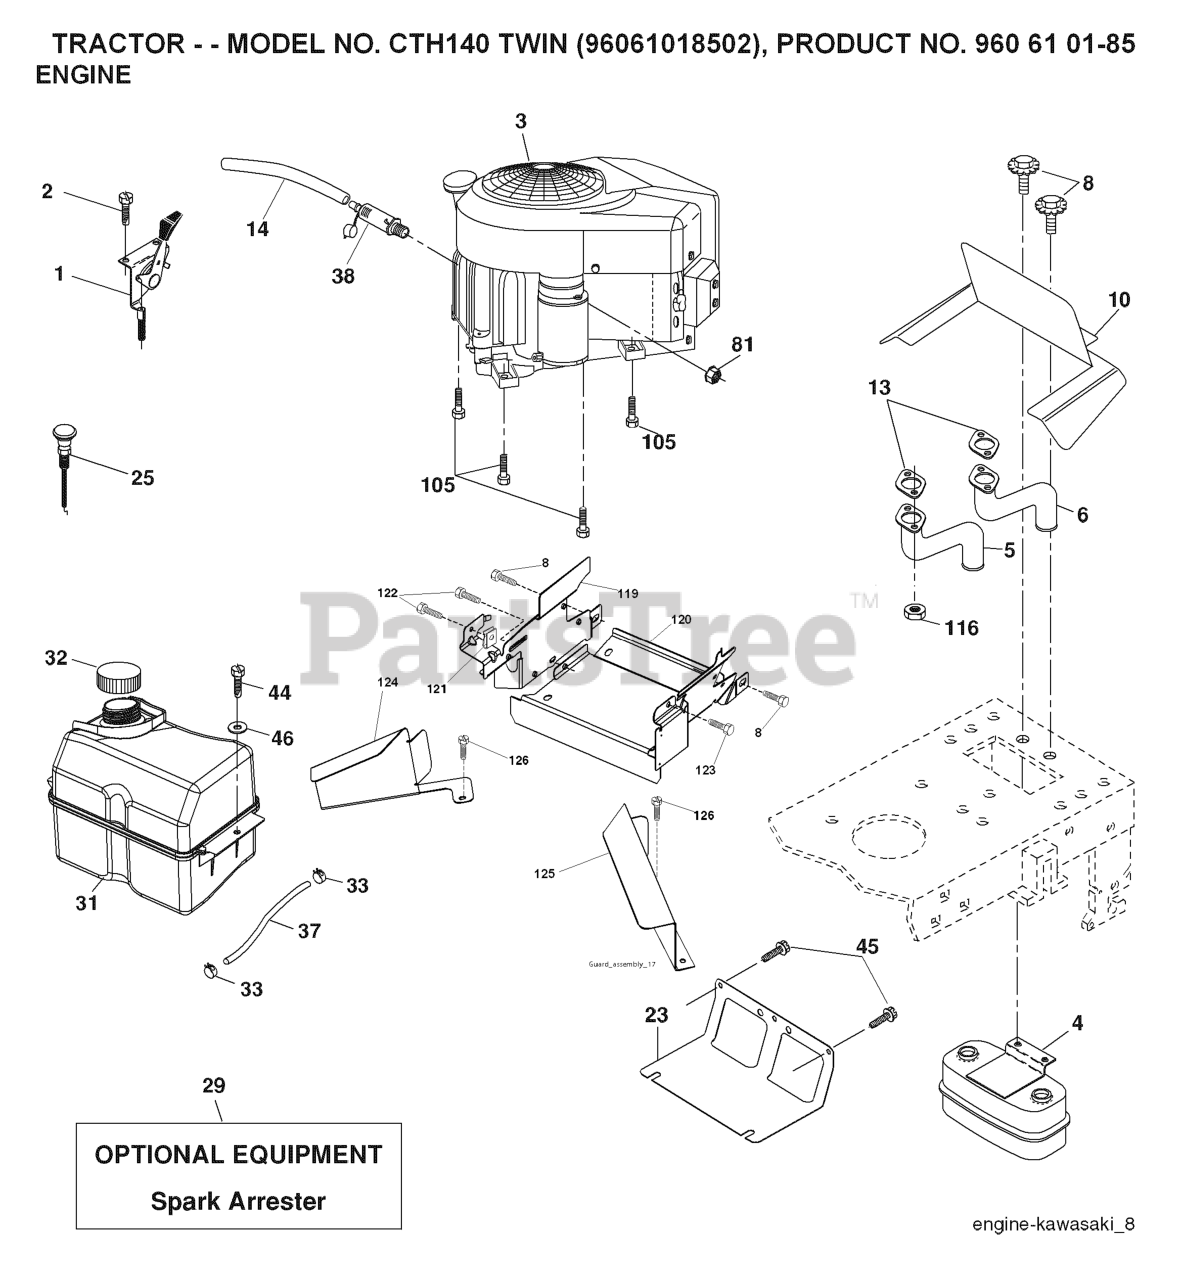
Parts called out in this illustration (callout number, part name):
1	CONTROL.THROTTLE.COBRA.BLACK
2	SCREW
4	MUFFLER.TWIN.CYL.LOW.TONE
5	EXHAUST TUBE LH KAWI
6	EXHAUST TUBE RH KAWI
8	BOLT.5/16-18UNCX3/4 W/SEMS.BLK
10	RP SHIELD HEAT MUFFLER
14	TUBE, DRAIN OIL ASM.
23	SHIELD.BROWNING.DBR.GUARD
25	CONTROL.CHOKE.ERGO.PUSH-IN.BLA
29	KIT.SPARK ARRESTOR 794945 B&S
31	RP TANK FUEL FRT 1.5 GAL
32	FUEL CAP
33	HOSE CLAMP
37	LINE.FUEL.20
44	SCREW HEXWSHR 1/4-20X3/4
45	SCREW, 3/8-16X3/4
81	NUT
105	SCREW 3/8-16X1
116	NUT.HEX.FLANGE.TOPLOCK
119	LENKRAD
120	GUARD 532199767
122	SCREW.1/4-20X5/8
123	SCREW, 5/16-18 X 1/2
126	SCREW
